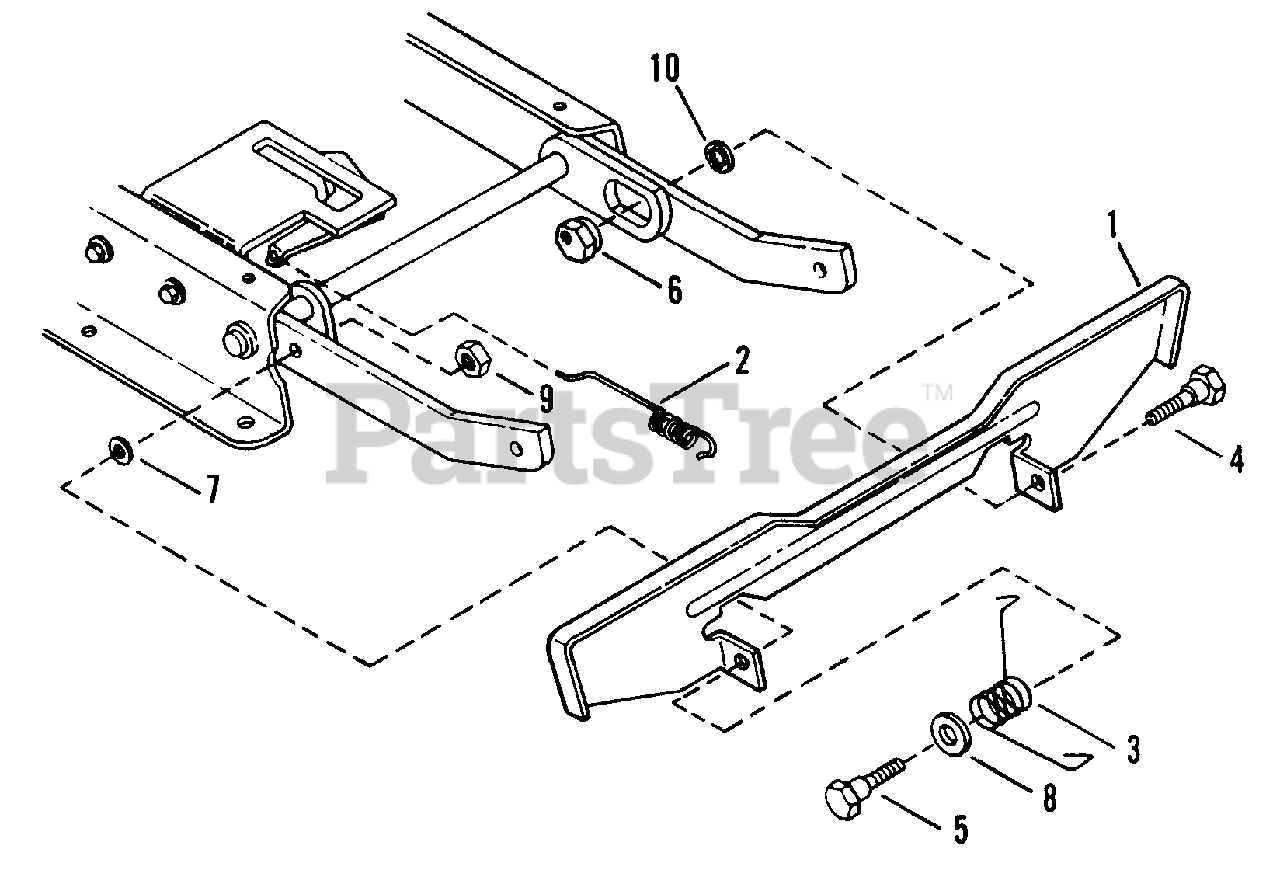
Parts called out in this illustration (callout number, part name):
1	PEDAL, Blade Stop Control
2	SPRING, Latching
3	SPRING, Pedal
4	BOLT, 3/8 - 24 x 3/4" Shoulder
5	BOLT, 3/8 - 24 x 9/16" Shoulder
6	ECCENTRIC, Leveling
7	WASHER, 3/8" Flat
8	WASHER, 1/2 Flat
9	NUT, 3/8 - 24 Hex Lock
10	WASHER, 3/8 Internal Tooth Lock
